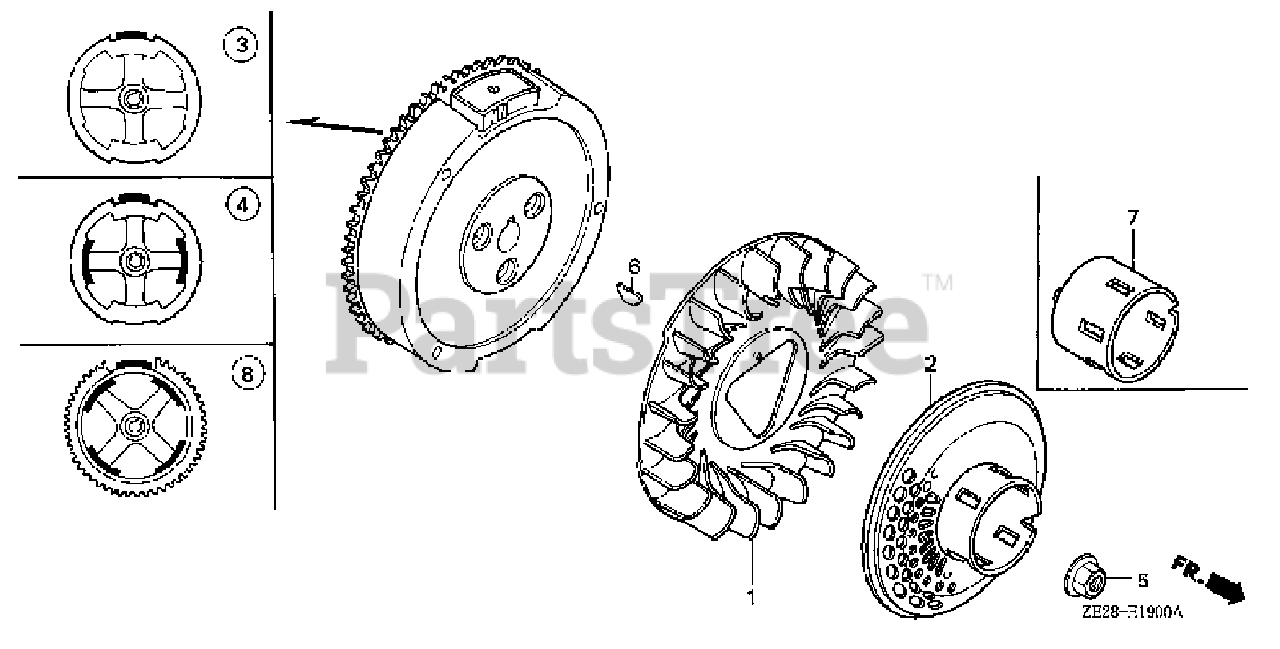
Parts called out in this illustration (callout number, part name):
1	FAN, COOLING
2	PULLEY, STARTER (SCREEN GRID)
3	FLYWHEEL
5	NUT, SPECIAL (16MM) (1)
5	NUT, SPECIAL (16MM)
6	KEY, SPECIAL WOODRUFF (25X18)
